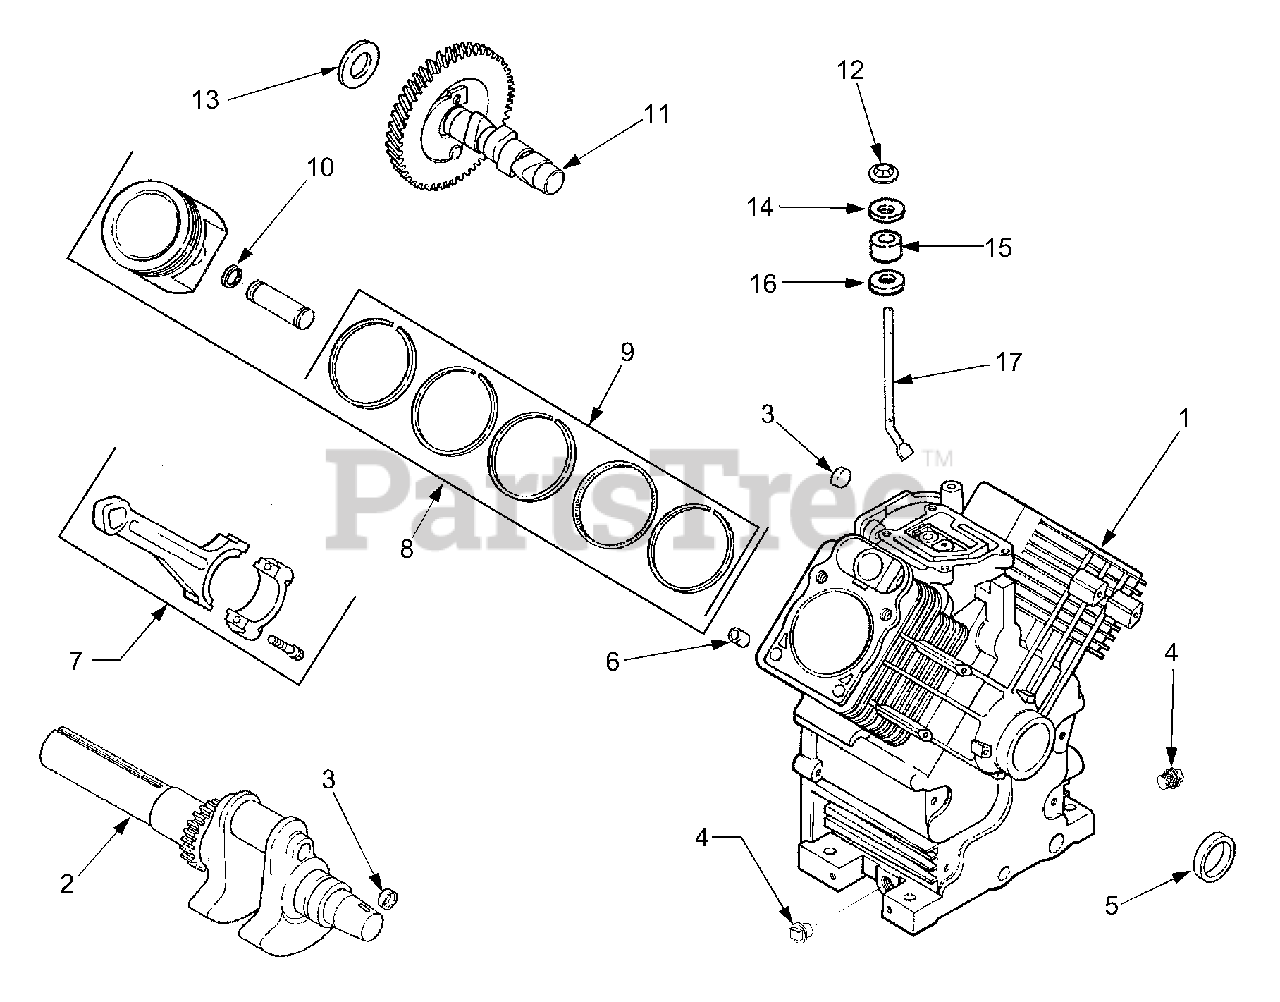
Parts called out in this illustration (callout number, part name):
1	Engine, Complete
2	Crankshaft
3	Plug, Cup
4	Plug, Hex Head, 3/8 NPTF
5	Seal, Oil
6	Pin, Dowel Locating
7	Rod, Connecting, Std
8	Piston w/Ring Set, Std
9	Ring Set, Std & .003
10	Retainer, Piston Pin
11	Camshaft
12	Ring, Retainer
13	Shim, Camshaft, .0320 red
14	Washer, Nylon
15	Seal, Governor Cross Shaft
16	Washer, Plain
17	Shaft, Governor Cross
